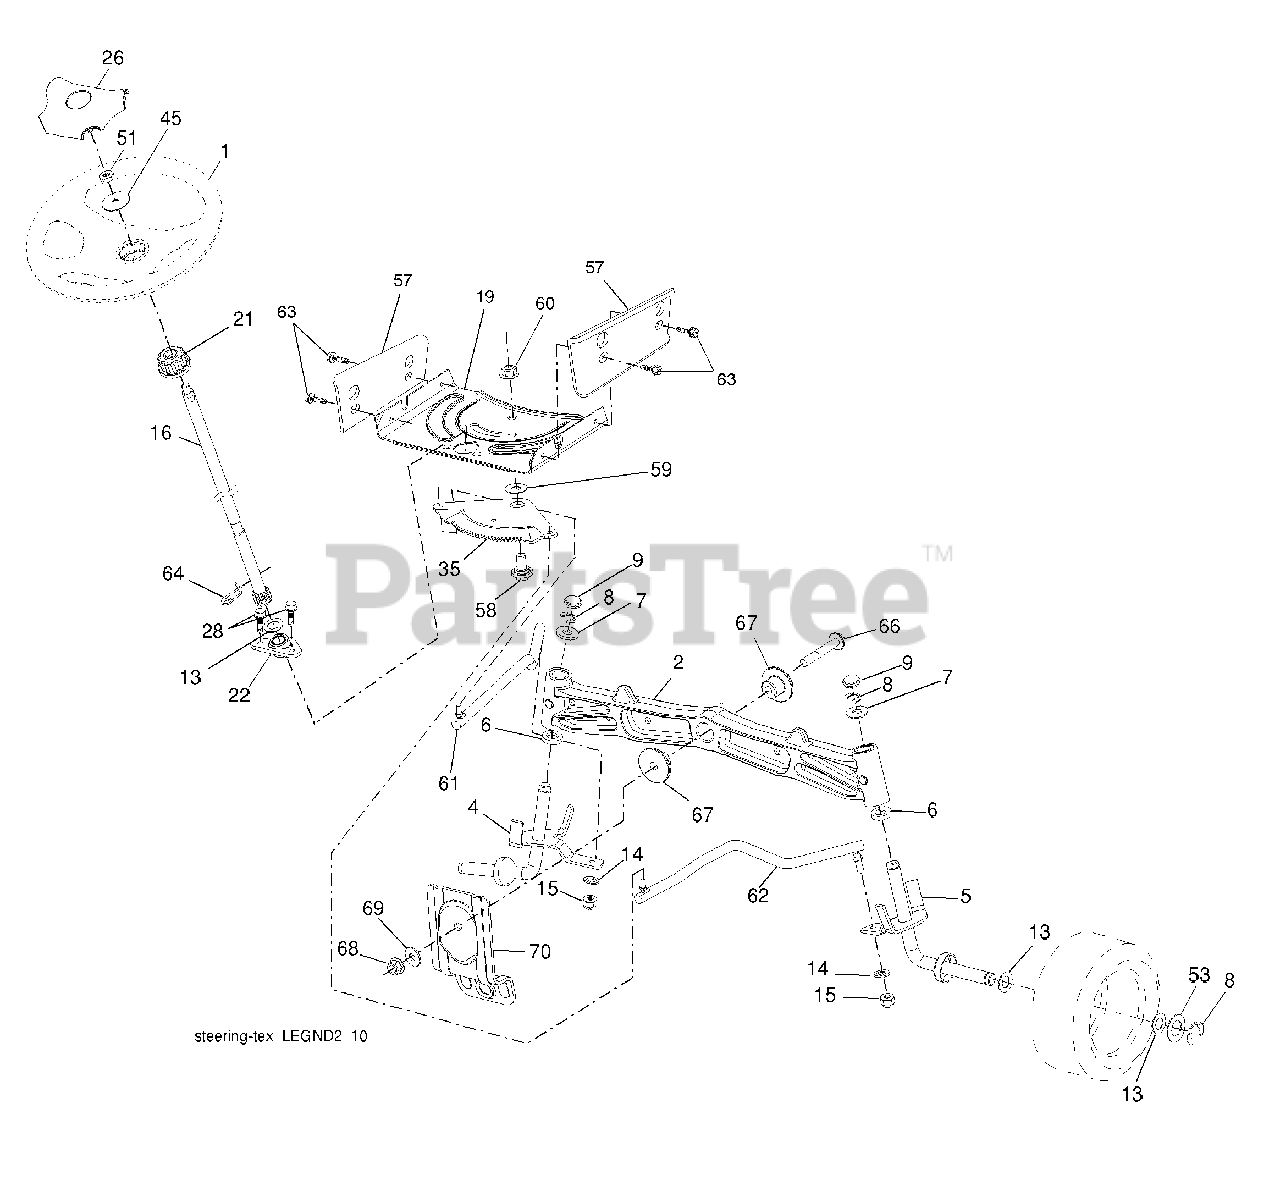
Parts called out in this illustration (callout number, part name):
1	Wheel, Steering
2	Axle Asm., Front
4	Spindle Asm., LH
5	Spindle Asm., RH
6	Bearing, Race Thrust Harden
7	Washer 25/32 x 1-5/8 x 16 Ga.
8	Ring, Klip #T5304-75
9	Cap, Spindle
13	Washer 25/32 x 1-1/4 x 16 Ga.
14	Washer, Lock Hvy Hlcl Spr 3/8
15	Nut, Crown Lock 3/8-24 unf
16	Shaft Steering
19	Plate Steering
21	Adapter, Wheel Steering
22	Bushing, Strg. Blk
26	Insert, Wheel Steering
28	Screw 3/8-16 x 3/4
35	Gear, Sector Plate
45	Washer 9/16 x 2-3/8 x 12 Ga.
51	NutHex Jam Toplock 1/2-20 unf
53	Washer Hardened .793 x 1.637 x .060
57	Bracket Upstop
58	Bolt Shoulder Sector Pivot CFM
59	Washer Thrust Sector Steering
60	Nut Flange Lock 5/8-11
61	Draglink LH
62	Draglink, RH
63	Screw 5/16-18 x 3/4
64	Retainer Clip Spring Steering
66	Bolt Hex Fghd 7/16-14 x 3 Serr
67	Bushing PM Front Axle
68	Nut Lock Flange 7/16-14 Gr. 5
69	Washer 1.5 x .505 x .118
70	Bracket Deck Susp. Front
